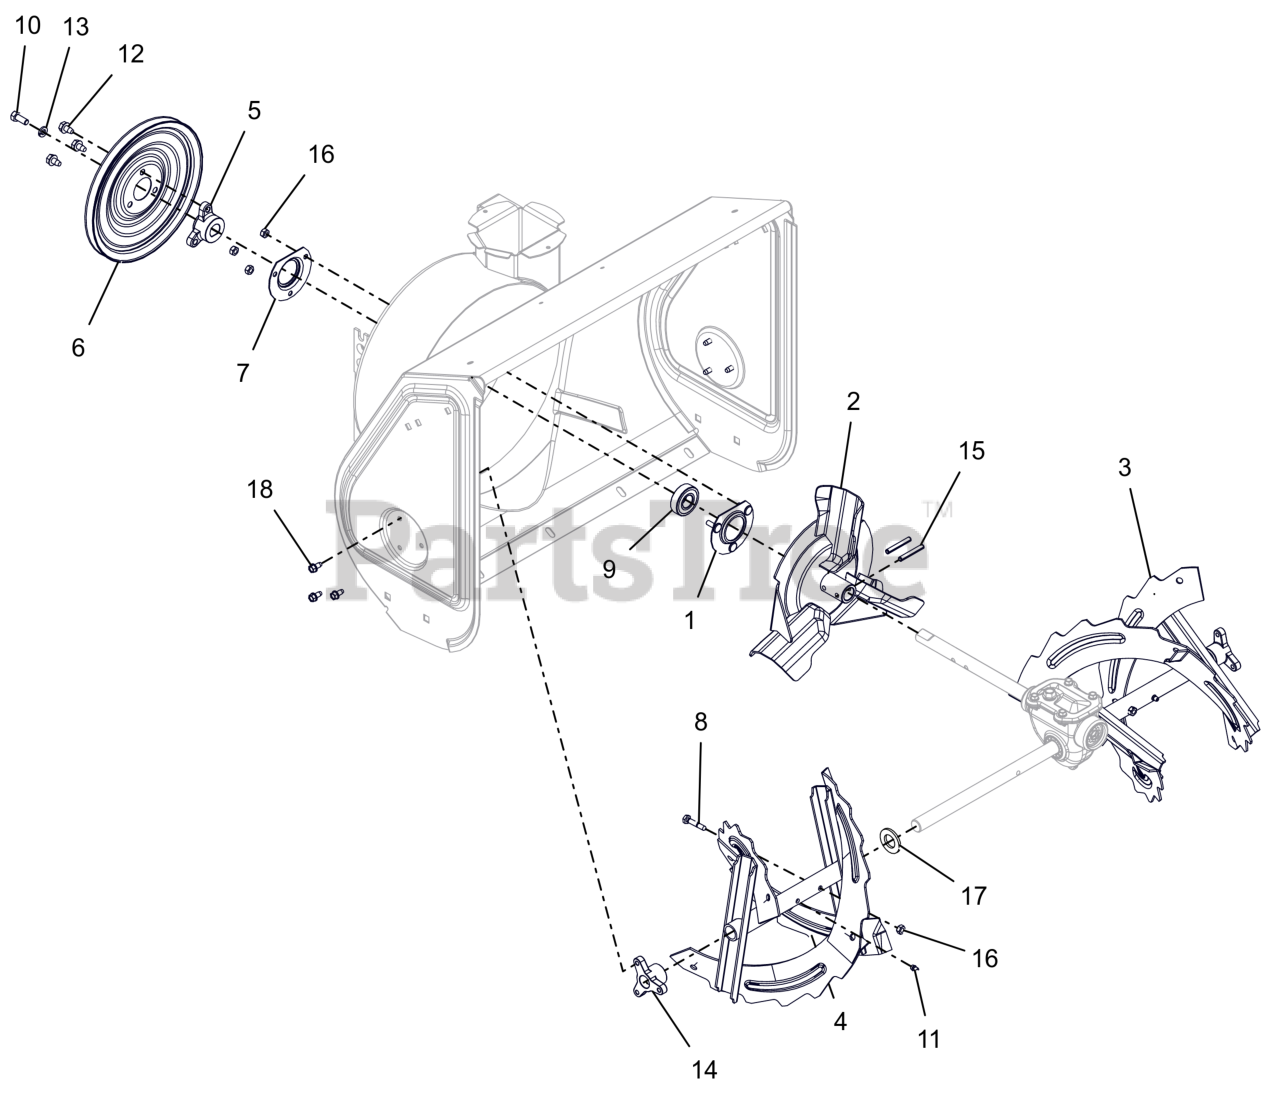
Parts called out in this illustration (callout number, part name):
1	BEARING FLANGE
2	IMPELLER, COMPACT 12" 3-BLADE
3	RAKE, 24" LH, BLK SERR W/ZERK
4	RAKE, 24" RH, BLK SERR W/ZERK
5	PULLEY HUB, BOLT-ON D-BORE .75
6	PULLEY,SPIN FORM SINGLE GROOVE
7	BEARING FLANGE
8	SHEAR BOLT WITH NUT
9	BRG-BALL .750X1.750X.50
10	BLT, HEX .31-24X.750 G5 ZCC
11	ZERK,FITTING .25X.125 DRIVE IN
12	SCR,TAP .312-18X.50 HWH TR ZCC
13	WSHR, LK-HVY .312X.097 ZCC
14	BUSHING, RAKE SHAFT .75"
15	PIN-ROLL .250X1.75
16	NUT,LK-CTR .25-20 GA ZCC
17	WSHR, FLT .812X1.469X.134 ZCC
18	SCR-TAP .25-20X.50 HWH ZCC
